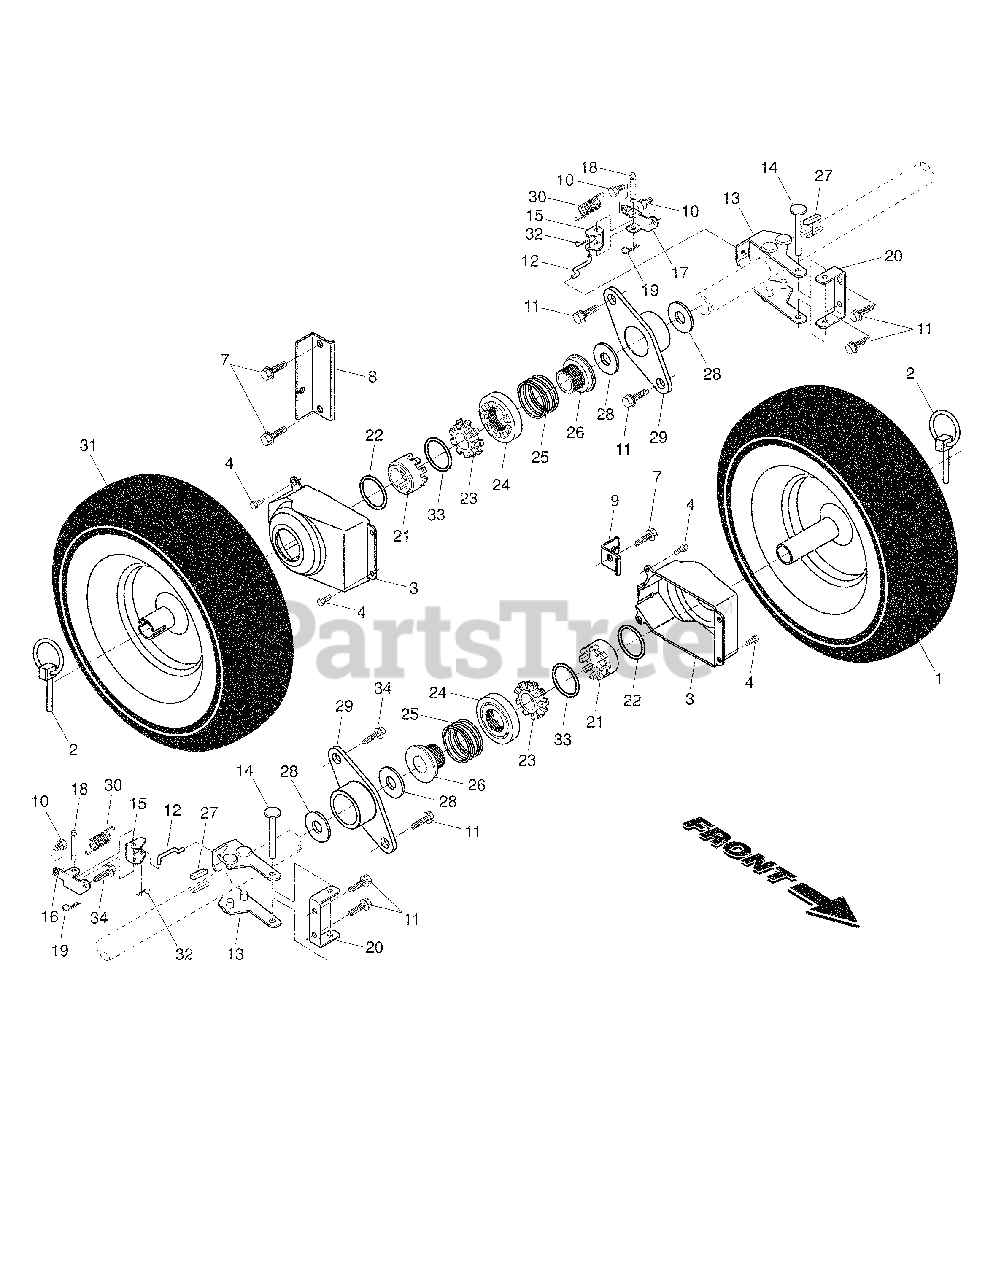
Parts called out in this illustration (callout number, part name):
1	Wheel Assembly, 16", Power Steering, LH
2	Pin, Klik 1/4
3	Cover, Power Steering
4	Bolt, Shoulder #10-24 x 5/8
7	Capscrew, Hex Head, Flanged 3/8-16 x 1
8	Bracket, Steering Cable, RH
9	Bracket, Steering Cable, LH
10	Screw, Hex Head 1/4-20 x 3/8
11	Screw, Hex Head 5/16-18 x 1/2
12	Link, Steering Lever
13	Yoke, Steering
14	Pin, Steering Lever
15	Bellcrank
16	Bracket Assembly, LH Steering
17	Bracket Assembly, RH Steering
18	Pin, Steering Bellcrank
19	Retainer, Hairpin
20	Bracket, Steering
21	Driver, Wheel
22	Ring, Wire Retainer
23	Lobe, Wheel
24	Slide, Clutch
25	Spring, Clutch Slide
26	Lobe, Axle
27	Key, Square
28	Washer, Thrust (1")
29	Bearing, Axle
30	Spring, Return
31	Wheel Assembly, 16", Power Steering, RH
32	Clip, Retainer
33	Ring, Retaining
34	Screw, Hex Head 5/16-18 x 5/8
